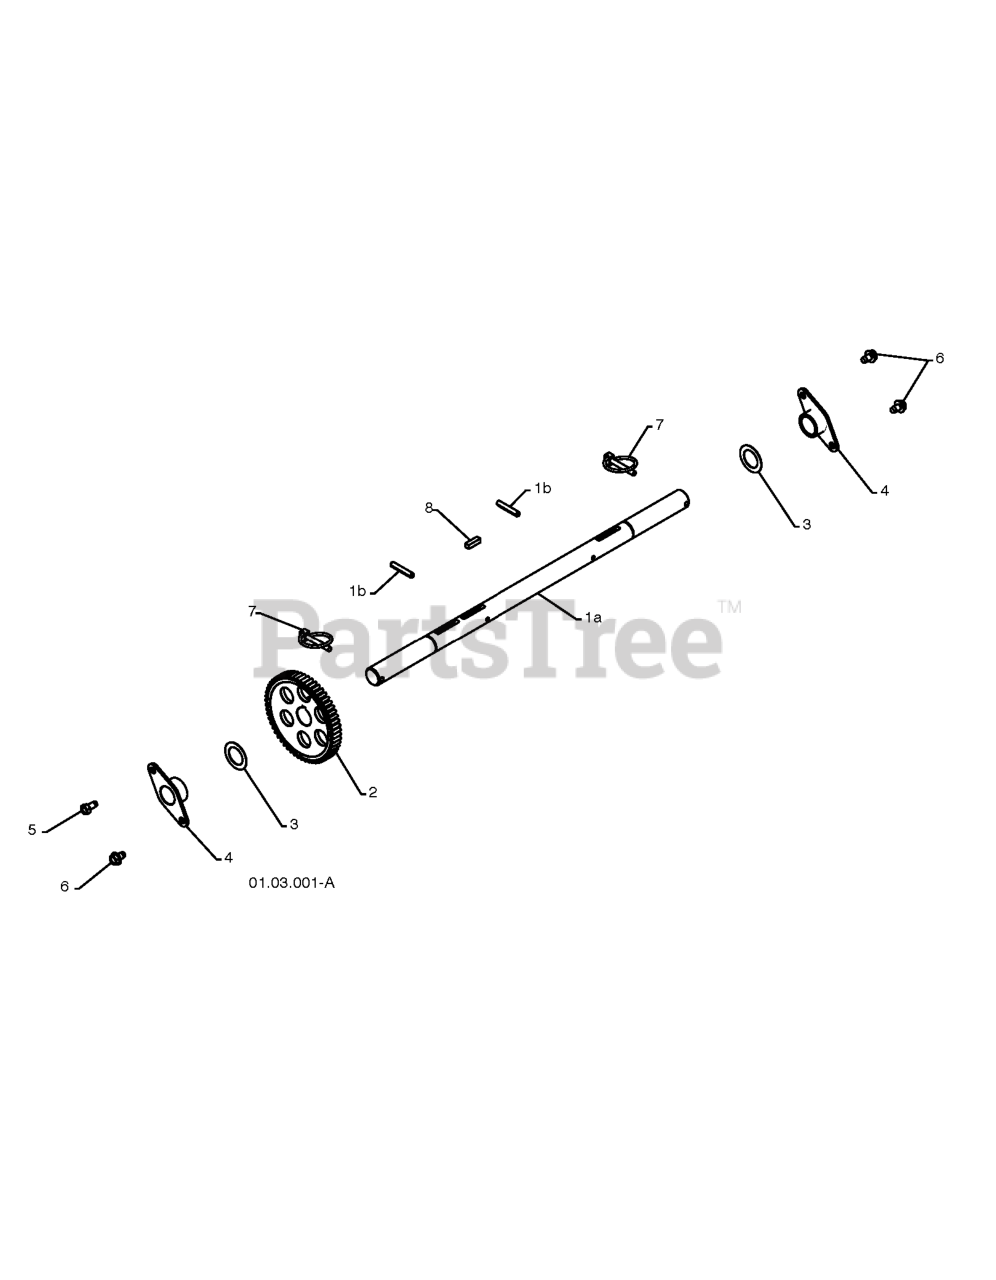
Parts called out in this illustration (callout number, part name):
1	AXLE.ASM.SHAFT.W/ROLLPIN.PS
2	GEAR, AXLE (58T)
3	WASHER TRUST 1"
4	BEARING, AXLE
6	Screw 5/16-18 x 1/2 Hex, Self Tapping 5/16-18 x 1/2
7	PIN KLIK, 1/4
8	KEY, SQUARE 1/4 X .875
